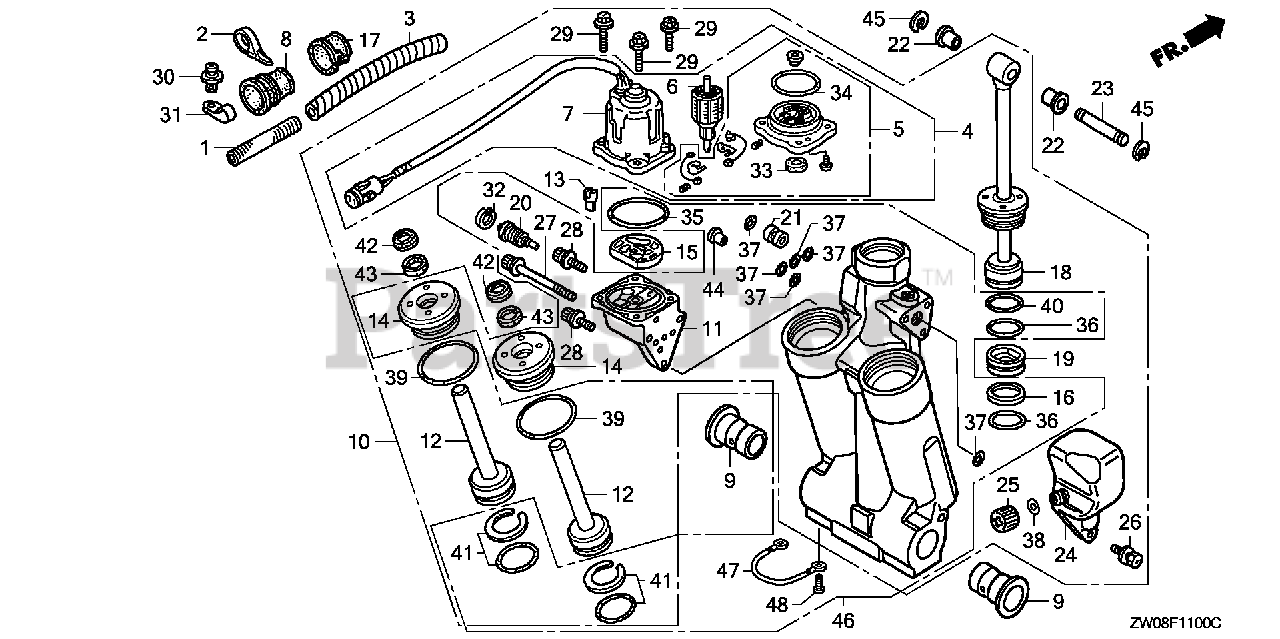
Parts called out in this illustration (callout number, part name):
1	TUBE, CORRUGATED (10MM)
2	BAND (BLACK 3.5X140)
3	TUBE, SPIRAL (12X14.6)
4	MOTOR ASSY., POWER TILT
5	BRACKET ASSY.
6	ARMATURE
7	YOKE ASSY.
8	GROMMET, CASE (LOWER) (C)
9	BUSH, SWIVEL CASE
10	TRIM-TILT, POWER
11	PUMP ASSY.
12	ROD, PISTON (B)
13	JOINT, DRIVE
14	GUIDE, ROD
15	FILTER (B)
16	RING, BACK-UP
17	BUSH, MOTOR CODE
18	ROD, PISTON
19	PISTON, FREE
20	VALVE, MANUAL
21	VALVE, RESERVOIR
22	BUSH, CYLINDER (LOWER)
23	PIN, CYLINDER (UPPER)
24	TANK, OIL
25	CAP, OIL TANK
26	BOLT, RECESSED
27	BOLT A, SOCKET
28	BOLT B, SOCKET
29	BOLT, HEX.
30	SCREW, RIVET (5X10)
31	CLIP (10.7MM)
32	CIRCLIP (INNER)
34	O-RING (2.0X70.5)
35	O-RING (1.8X69.6)
36	O-RING (3.5X38.7)
37	O-RING (1.8X7.7)
38	O-RING (1.9X11)
39	O-RING (3.5X35.7)
40	O-RING (3.5X41.7)
41	O-RING SET (3.5X31.7)
42	SEAL, WATER
44	COLLAR, ORIFICE
45	E-RING (15MM)
46	CYLINDER ASSY. KIT, POWER TRIM-TILT
47	WIRE, LEAD (1.5X116MM)
48	SCREW, PAN (6X8)
